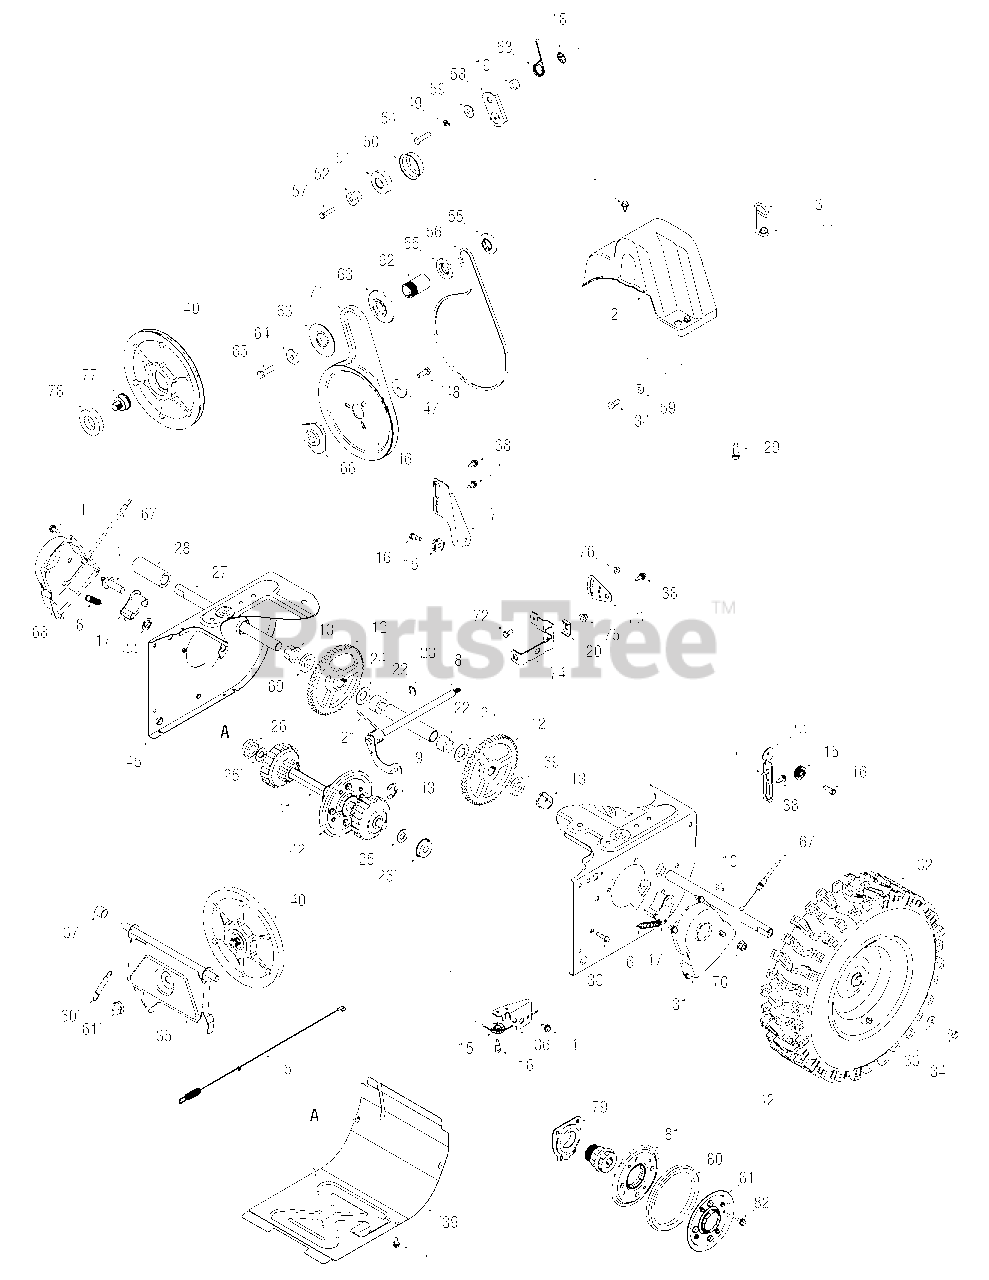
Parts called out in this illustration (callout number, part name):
1	AB Screw, 1/4-20 x 0.625
2	Belt Cover
3	Cable Guide
4	Actuator Shaft
5	Drive Clutch Cable
6	Extension Spring
8	Shift Rod Assembly
9	Axle Support Tube
10	Hi Pro Key
11	TT Screw, 5/16-18 x 1.00
12	Gear, 56T
13	Hex Flange Bearing
15	Cable Roller
16	C Screw, 1/4-28 x 0.375
17	Dogg Assembly - LH
17	Dogg Assembly - RH
18	Push-on Nut
19	Spacer
20	Shift Bracket Spacer
21	Torsion Spring, .750ID x .968 Lg.
22	Spacer
23	E Ring
24	Flat Washer, .76 x 1.49 x .06
25	Flat Washer
26	Ball Bearing
27	Axle
28	Spacer
29	TT Sems Screw, 3/8-16 x 1.0
30	TT Screw, 1/4-20 x 1.0
33	Bell Washer
34	Hex Bolt, 5/16-24 x 0.75
37	Spacer
38	Shoulder Screw
41	Drive Shaft Assembly
42	Friction Wheel Assembly
43	Retainer Ring
44	Speed Nut
46	Auger Pulley
47	Flat Washer
48	Hex Bolt, 5/16-24 x 0.875
49	Lock Washer
50	Bearing Sleeve
51	Ball Bearing
52	Spacer
53	Torsion Spring
54	Hex Screw, 5/16-24 x 1.25
55	Pulley Half
56	V-Belt, 2L x 33
57	TT Screw, 1/4-20 x 1.25
58	Drive Clutch Idler Bracket
59	Shoulder Spacer
60	Extension Spring
61	Jam Lock Nut, 5/8-18
62	Spacer
63	Pulley Half
64	Flat Washer
65	Hex Bolt, 3/8-24 x 1.25
66	Pulley Adapter
67	Steering Cable
69	Axle Spacer
70	Flange Lock Nut, 3/8-16
71	V-Belt,.500 x 35.00 Lg
72	Hex Screw, 1/4-20 x .620
75	Flange Lock Nut, 5/16-18
76	Flange Lock Nut, 1/4-20
77	Friction Pin
78	Ball Bearing
79	Friction Wheel Bearing Assembly
80	Friction Wheel
81	Friction Plate
82	Screw, 1/4-14 x .625
